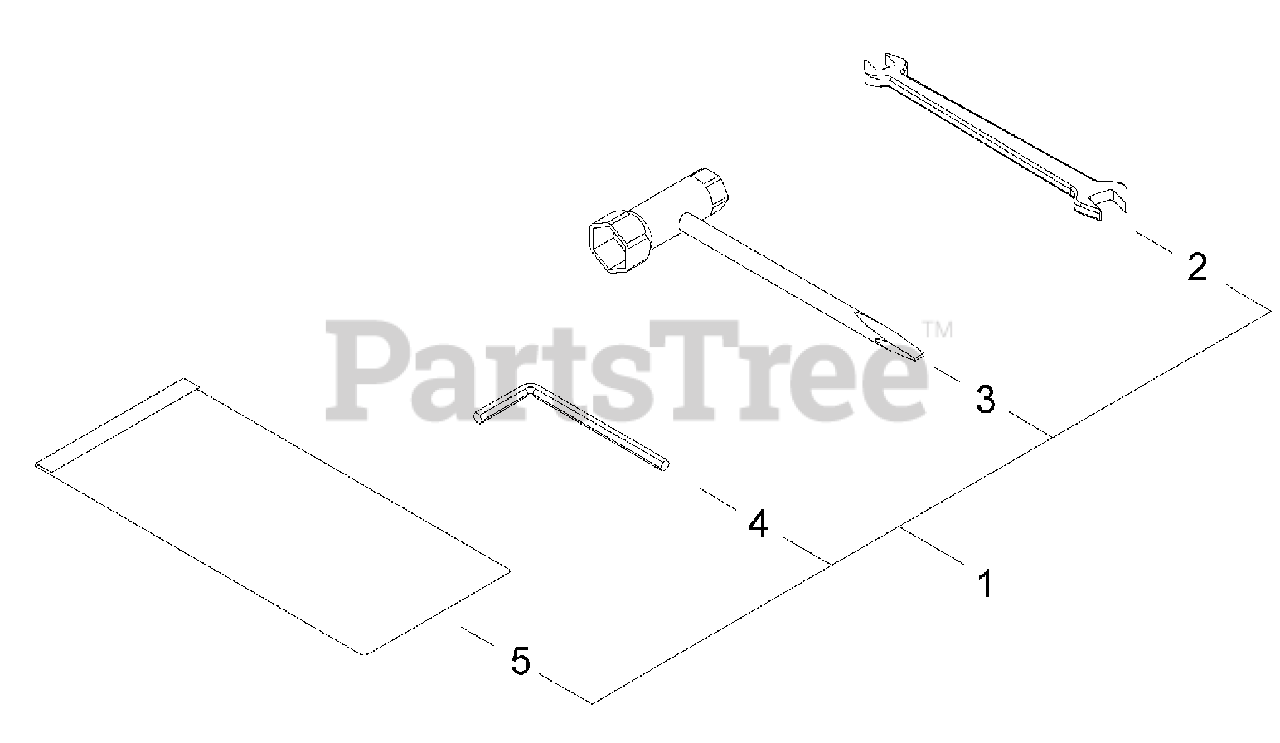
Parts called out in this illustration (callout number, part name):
1	TOOL KIT
2	SPANNER - 8X10mm
3	T-WRENCH - 13X16mm
4	HEX KEY - 4mm
5	BAG, TOOL
